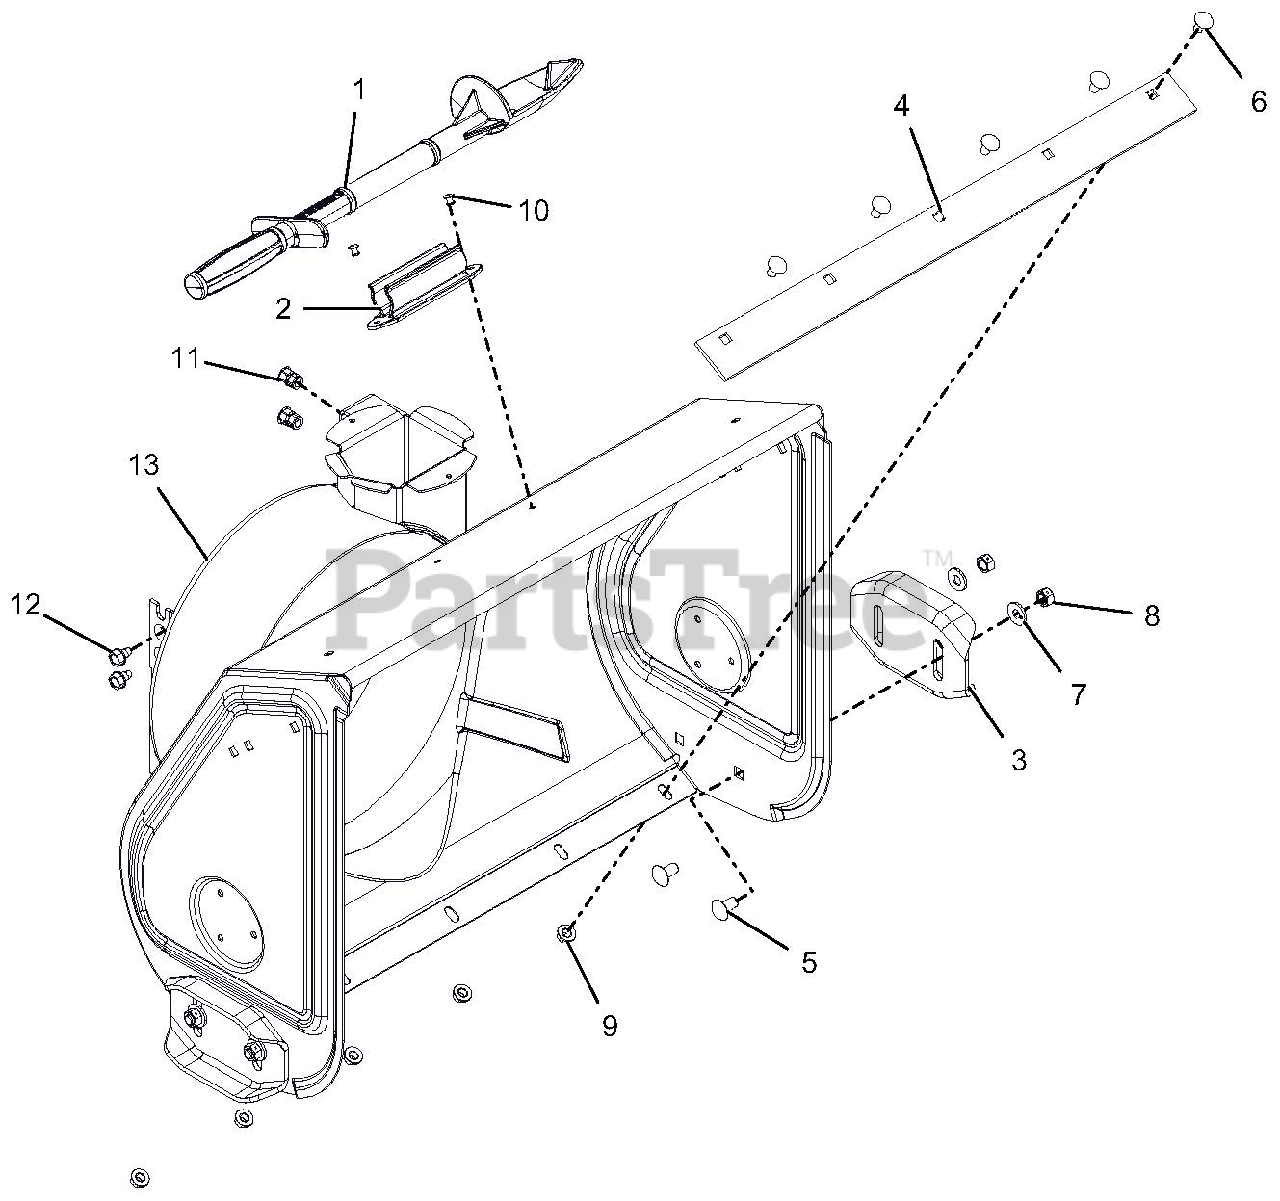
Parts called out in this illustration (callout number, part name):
1	DEVICE, SNOW CLEAN OUT
2	MOUNT, SNOW CLEAN OUT
3	SKID SHOE, REVERSIBLE - ORANGE
4	SCRAPER BLADE, 24" COMPACT HI
5	@BLT-RHDSSQNK .38-16X.75 G5YZ
6	BLT,RDSHHDSQSHNK .31-18X.62 YZ
7	@WSHR-FL-STL.38X.875X.083 YWZC
8	@NUT-LK-CTR .38-16 YWZC
9	@NUT-LK-TOP-FLG .31-18 YWZC
10	RVT-POP .187 YZ
11	NUT, THREADED INSERT .38-16
12	@SCR-TAP .31-18X.50 HWH TR YWZ
13	BLOWER HOUSING, 24" HI ORANGE
